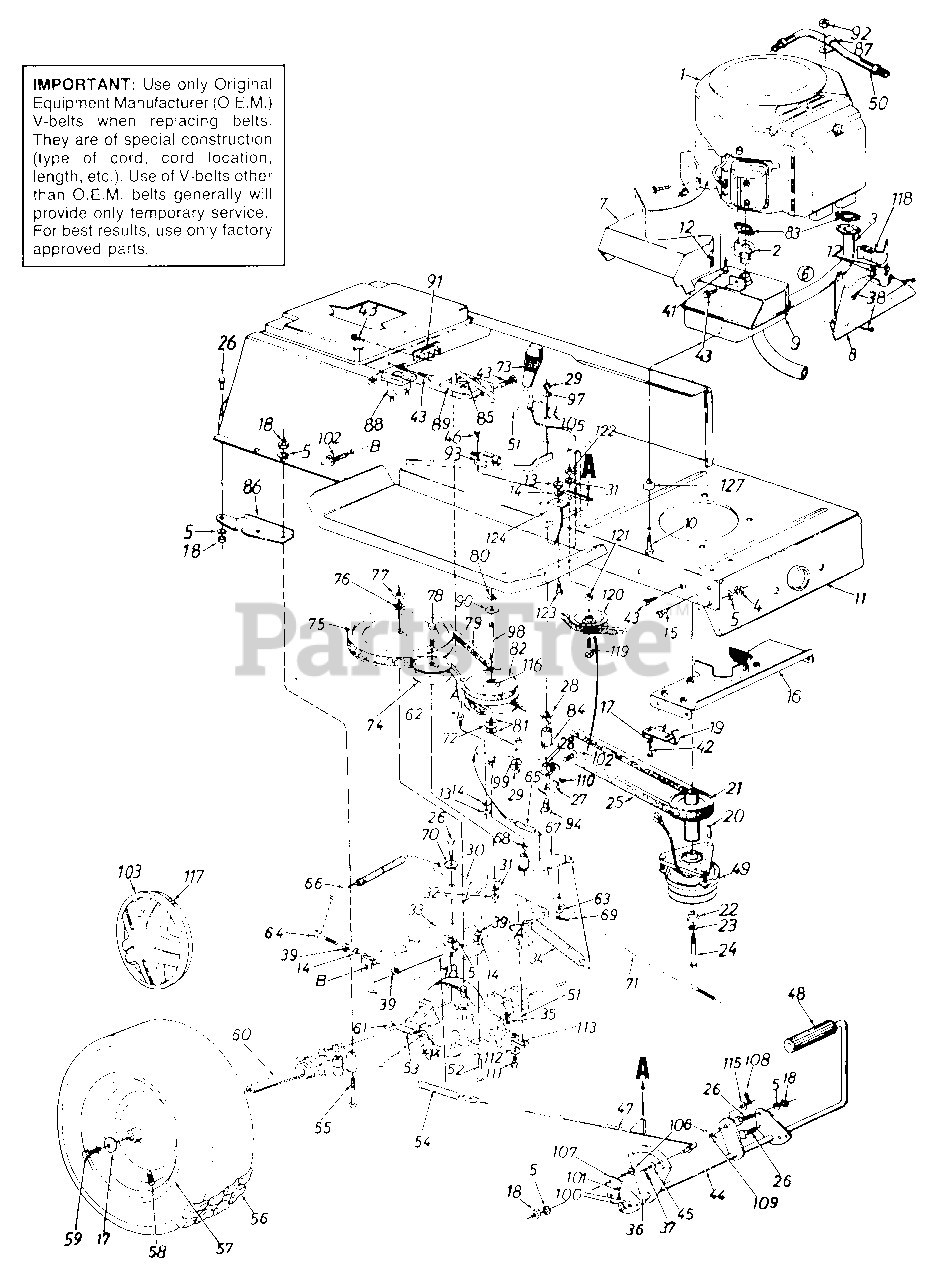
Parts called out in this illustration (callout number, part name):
1	Engine
2	Inlet Tube Ass'y.
3	Formed Tube Ass'y.
4	Hex Nut 5/16-24 Thd.
5	L-Wash. 5/16" I.D.
6	Muffler Ass'y. Comp.
7	Muffler Heat Shield
8	Front Heat Shield
9	Exhaust Muffler Sub Ass'y.
10	Hex Wash Hd. AB-Tap Scr. 3/8-16 Thd.
11	Lower Frame Ass'y.
12	Speed Nut #10-24 Thd.
13	Hex Nut 1/4-20 Thd.
14	L-Wash. 1/4" I.D.
15	Rib Neck Bolt 5/16-24 x .84" Lg.
16	Belt Keeper Brkt. Ass'y.
17	Bell-Wash. .345" I.D. x .88"
18	Hex Nut 5/16-18 Thd.
21	Engine Pulley
22	Shld. Spacer .445" I.D.
23	L-Wash. 7/16" I.D.
24	Hex Bolt 7/16-20 x 5.0" Lg.
25	Variable-Speed Belt
26	Hex Bolt 5/16-18 x .75" Lg.
27	Bearing Shaft Bracket Ass'y.
28	Flanged Nyliner Brg. 5/8" I.D. x .88" Lg.
29	Hex Nut 3/8-24 Thd.
31	L-Wash. 3/8" I.D.
32	Hex Nut 3/8-24 Thd.
33	Transaxle Support Brkt.
34	Ext. Spring .94" O.D. x 7.58"
35	Inter. Cotter Pin
36	Spacer .63" I.D.
37	Cotter Pin 3132" Dia. x .75"
38	Hex AB-Tap Scr. #10 x .5" Lg.
39	Hex Nut 1/4-28 Thd.
41	Hex Bolt w/Washer
42	Hex Bolt 5/16-18 x .75" Lg. (Grade 5)
43	Hex Wash. Hd. S-Tap Scr. 1/4-20 x .50" Lg.
44	Clutch/Brake Pedal Ass'y.
45	Fl-Wash.
46	Truss Mach. Scr. B-Tap Scr. #10 x .5" Lg.
47	Brake Rod Ass'y.
48	Foot Pad
49	Electric Clutch
50	Hydraulic Hose 13" Lg.
51	Shift Lever Ass'y.
52	Hex Bolt 1/4-28 x 1.75" Lg.
53	Ext. Spring .38" O.D. x 2.5"
54	Ext. Spring .59" O.D. x 7.08"
55	Hex Bolt 5/16-18 x 2.75"
57	Wheel Rim Only
58	Air Valve
59	Hex Bolt 5/16-24 x .75" Lg.
60	Transaxle Complete
61	Brake Return Spring Anchor
62	Belt Guard Pin 1/4-20 Thd.
63	Fl-Wash. .34" I.D. x .68" O.D.
64	Hex Bolt 1/4-28 x 1.25" Lg.
65	Ext. Spring
66	Ext. Spring .62" O.D. x 6.12"
68	Flanged Bearing
69	Cotter Pin 3/32" Dia."
70	Shoulder Spacer .27" Lg.
71	Speed Control Link
72	Truss Bearing .56 Dia. x 1 .25"
73	Shift Knob
74	Fl-Idler Pulley 3.25" x .75"
75	1/2""V"-Pulley
76	L-Wash. 1/2" I.D.
77	Hex Jam Nut 1/2-20 Thd.
78	Hex Bolt 3/8-24 x 1.75" Lg.
79	Variable Speed Belt
80	Snap Ring .56" Dia.
81	Fl-Wash.
82	Variable Speed Pulley Ass'y. 5" O.D.
83	Gasket
88	Solenoid
90	Teflon Washer .565" I.D.
91	Circuit Breaker
92	Hex Jam Nut 3/8-16 Thd.
93	Safety Switch (Clutch)
94	Shld. Bolt 3/8-24 x 3.12" Lg.
97	Bell-Wash. .38" I.D. x .88"
98	Shaft .56" Dia. x 3.875" Lg.
99	Bell-Wash. .39" I.D. x 1.12"
100	Fl-Wash. .64" I.D. x.94"
101	Cotter Pin 3132" Dia. x 1.0"
102	Hex Wash. Hd. Scr. 5/16-18 x .62" Lg.
103	Hub Cap
105	Belt Guard
106	Truss Mach. Scr. 5/16-18 x .75" Lg.
107	Pedal Bracket
108	Cotter Pin 31321' Dia. x .75"
109	Ferrule
110	Hex Bolt 5/16-18 x 1.0" Lg. (Grade 5)
111	Hex Bolt 1/4-28 x .50" Lg.
112	Bell-Wash. .265" I.D. x .75"
113	Shift Lever Link Ass'y.
115	Fl-Wash. .385" I.D. x .62"
116	Needle Brgs.
117	Spring Clip
118	Front Heat Shield Ext.
119	Hex Bolt 3/8-16 x 1.25" Lg.
120	Fl-Idler w/Flanges 2.75" O.D.
121	Fl-Wash. .39" I.D. x 1.12" O.D.
122	Hex Nut 3/8-16 Thd.
123	Hex Bolt 1/4-20 x .62" Lg.
124	Spring Hanger Brkt.
127	Spacer 5/16" I.D.
